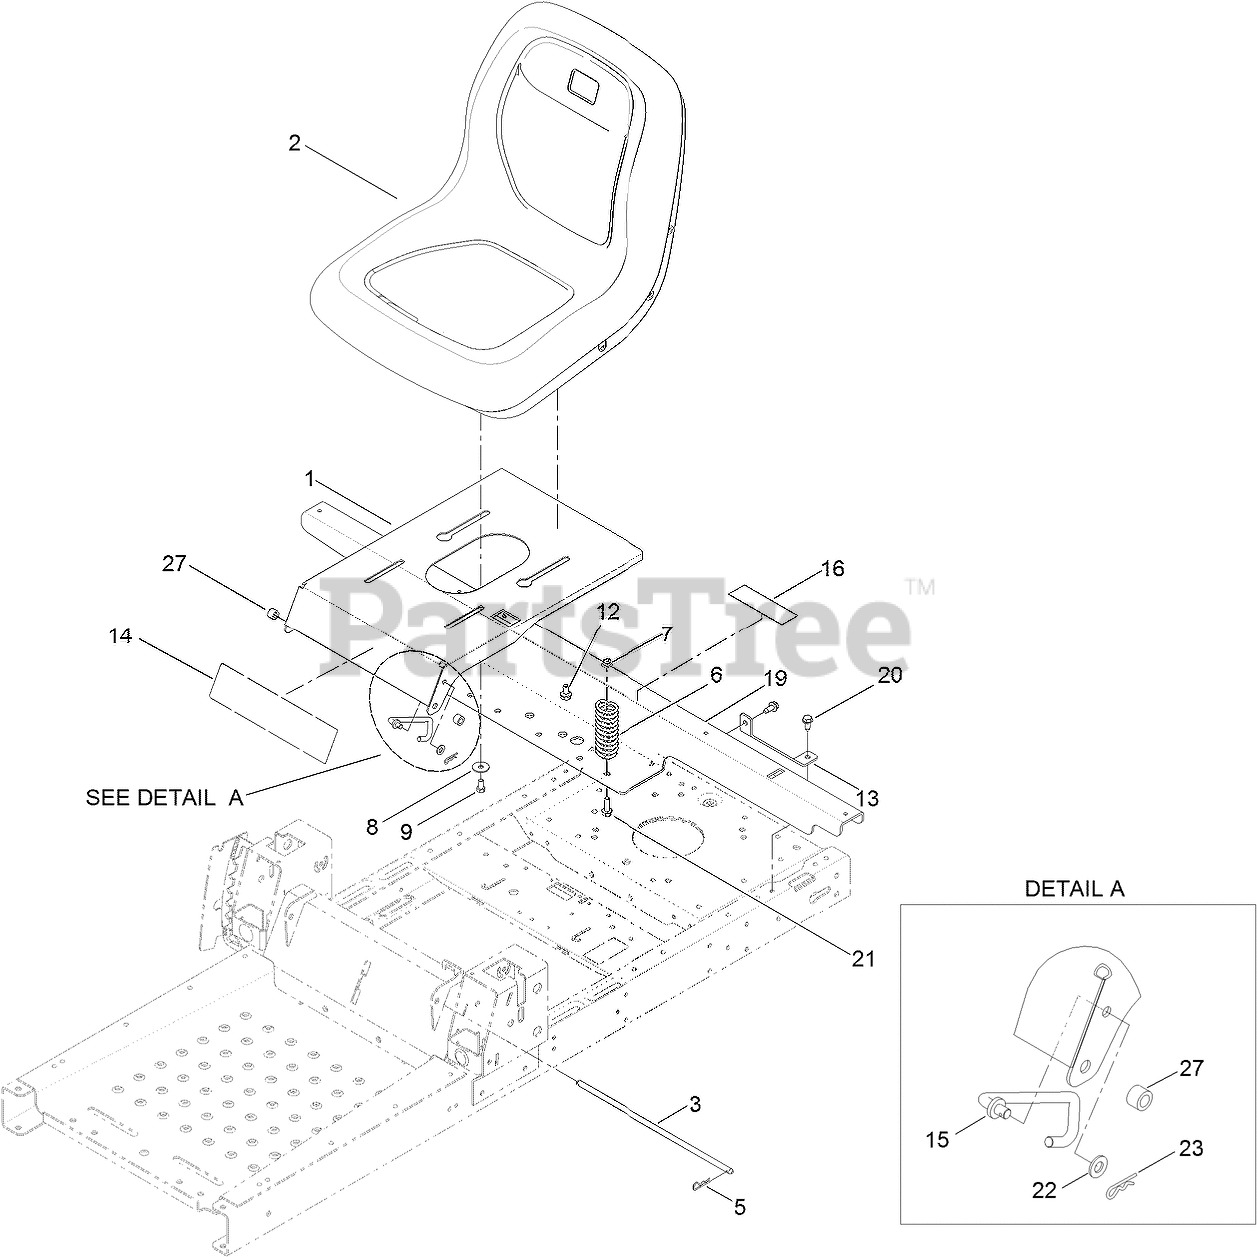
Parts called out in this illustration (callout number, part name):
1	PAN-SEAT
2	SEAT-18 INCH
3	ROD-STOP
5	PIN-COTTER
6	SPRING-COMPRESSION
7	NUT-HF, NI
8	WASHER-PIVOT
9	SCREW-HH
12	BOLT-SHOULDER
13	SUPPORT-TANK, REAR
14	DECAL-TIMECUTTER
15	STOP-SEAT
16	DECAL-SERVICE, CE
19	SUPPORT-POD
20	SCREW-HWHTF
21	SCREW-HHF
22	WASHER-PLAIN
23	PIN-COTTER
27	SPACER
